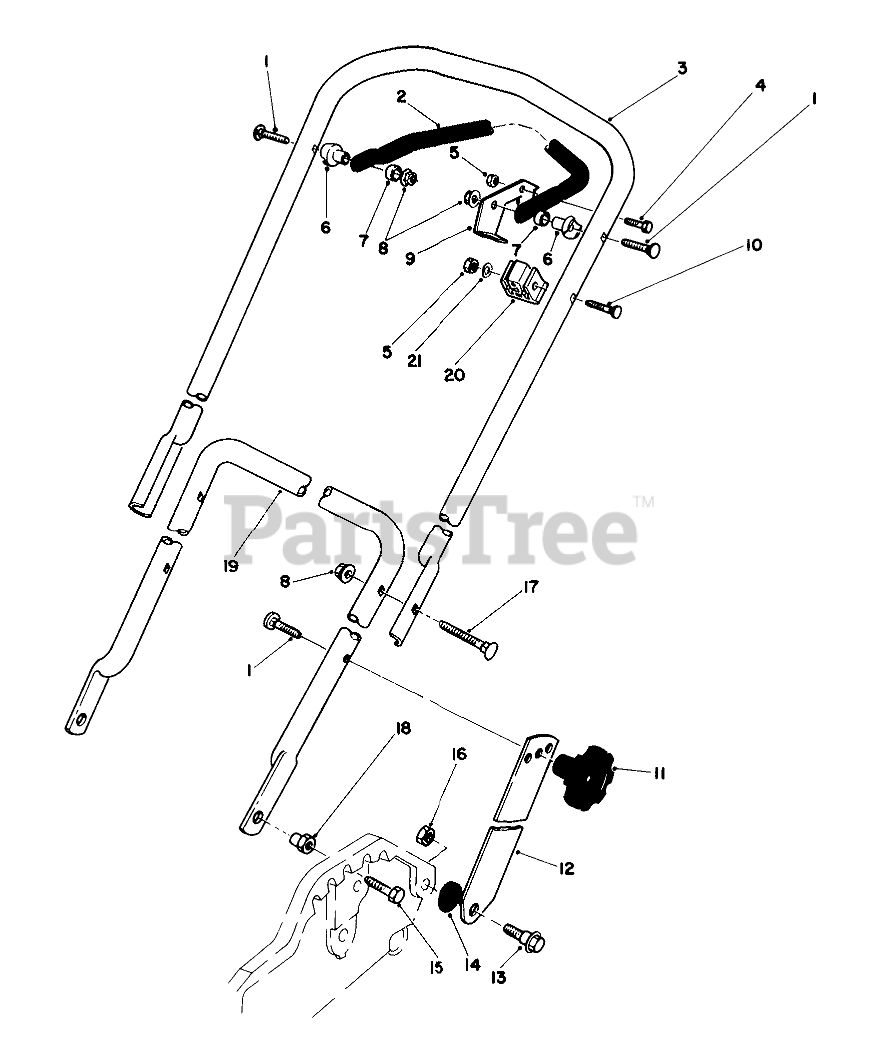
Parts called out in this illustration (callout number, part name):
1	5/16-18 X 2 HNDLE SCREW
2	CONTROL BAR
3	UPPER HANDLE
4	SCREW-HH
5	NUT-LOCK, NI
6	SPACER-SUPPORT
7	SPACER-NYLON
8	NUT-LOCK, NI
9	Lever-Control
10	HANDLE SCREW
12	Handle Latch
13	SCREW-SHOULDER
14	SPACER
15	SCREW-HH
16	NUT-LOCK, NI
17	SCREW
18	HANDLE PIVOT NUT
19	LOWER HANDLE
20	SUPPORT-CABLE
21	WASHER-FLAT
